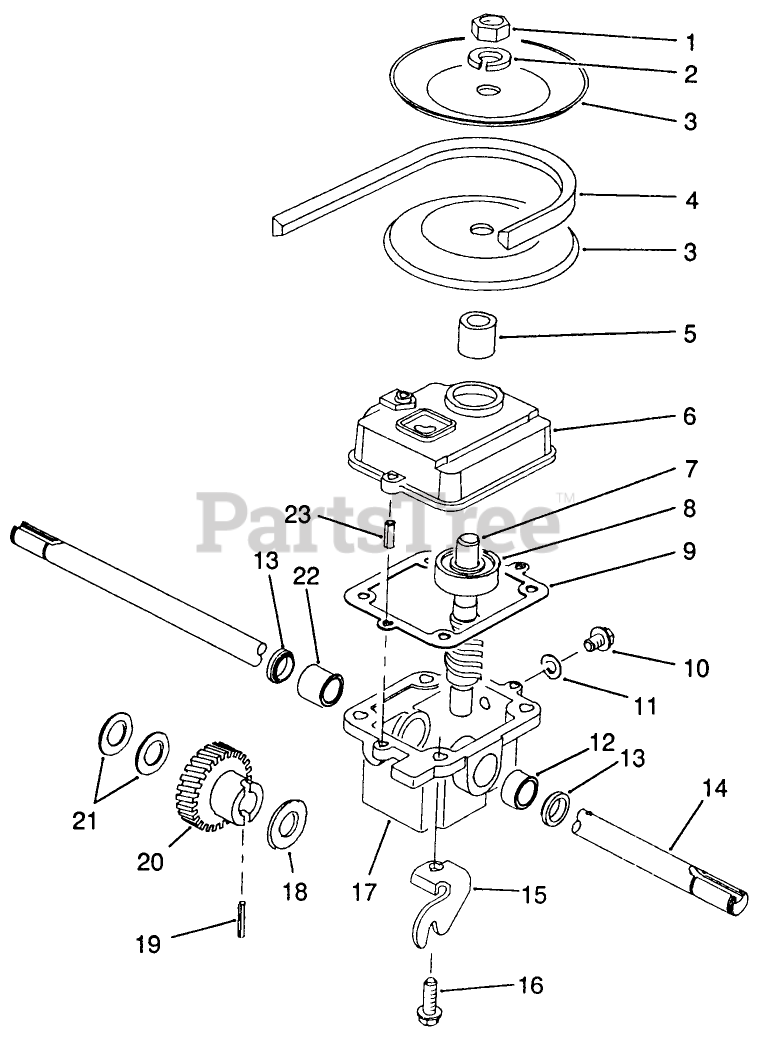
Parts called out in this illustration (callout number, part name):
1	NUT-JAM
2	WASHER-LOCK
3	PULLEY-DRIVEN HALF
8	BEARING - BALL
9	GASKET
10	NYLON SCREW
11	FILL PLUG GASKET
12	BUSHING
13	SEAL-OIL
16	SCREW-HWHTF
18	THRUST WASHER
19	PIN-SPRING
20	GEAR - HELICAL
21	WASHER-PLAIN
22	BUSHING
23	3/16 X 1/2 ROLL PIN
